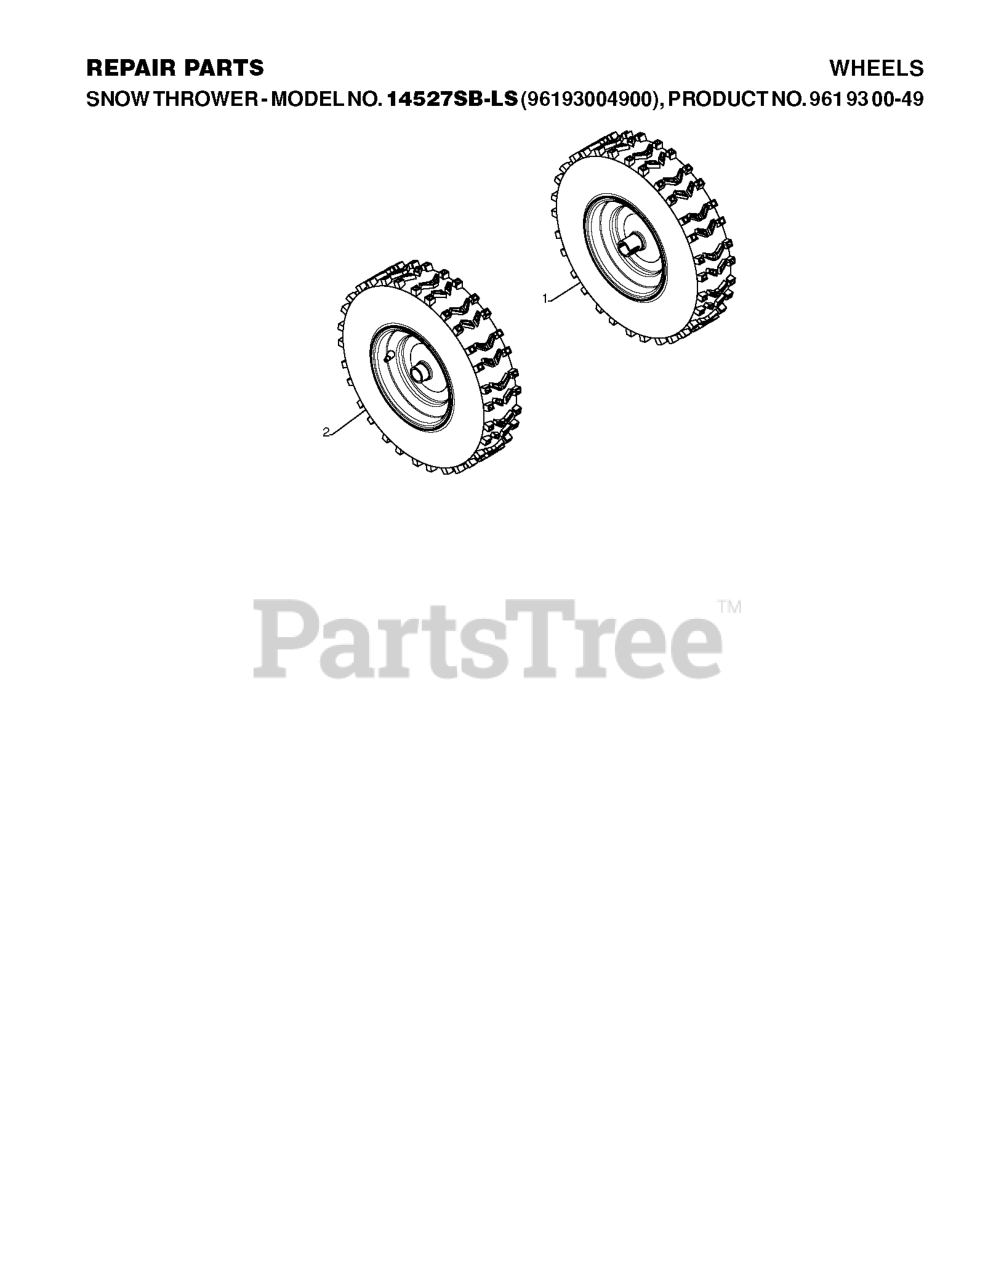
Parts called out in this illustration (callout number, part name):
1	WHEEL.ASM.LT.16"
2	WHEEL.ASM.RT.16.SILV.XTRAC.PS
8	ROD SHIFT FENDER ADJUST LT
9	CLUTCH.ELECTRIC.OGURA.EURO.
10	PIN COTTER
14	LOCKWASHER
15	BOLT HEX 5/16-18 GR 5
16	NUT.71038.31-18.HEX.NYLOCK
19	NUT
20	BOLT HEX 7/16-20X4-1/4"
21	KNOB.DUCKHEAD.1/2
22	ROD
24	NUT
25	SPRING BRAKE ROD
27	COTTER PIN
28	ROD, PARKING BRAKE
29	CAP
30	BRKT, TRNSXLE MNT 20"
34	SHAFT, FOOT PEDAL
35	BEARING.NYLON
37	DRIVE PIN
38	PULLEY.FLAT
42	WASHER
47	IDLER PULLEY
48	BELLCRANK, CLUTCH
49	RETAIN BELT
50	BOLT.3/8-16X1.50
52	LOCKNUT
53	LINK.CLUTCH.7.66.2005
55	SPRING, RETURN LT
56	SCREW.3/8-16
57	V-BELT 113"
62	PEDAL COVER T
63	PULLEY.ENGINE.CVX.LT
65	LOCKWASHER
66	KEEPER BELT ENGINE
71	STRAP TORQUE LH HYDRO
73	STRAP TORQUE RH HYDRO
74	SPACER AXLE
77	SQUARE KEY
81	ASM.CROSS.SHAFT.REAR.CRD.0510
82	SHIFT SPRING
83	WASHER
84	LINK.PNT.TRANSAXLE.0510.CRD
95	LINK
96	RETAINER M
120	NUT LOCK FLG 3/8-16 UNC
150	BUSHING.BELLCRANK.GRD.DR
151	WASHER 12/32X2X10GA
156	WASHER.SRRTD.5/16
158	BRACKET
159	RB HUB.SHIFT
161	BOLT
162	NUT.CROWNLOCK.1/4
165	RP BRACKET
166	CAPSCREW.HXHD.FLG.5/16-18X.625
167	BRACKET.SUPT.SHIFT.CRD
168	BOLT.SHOULDER.5/16-18X
169	PLATE.FASTENING.CROSS.SHAFT
172	LINK
181	BRACKET
182	BELT GUIDE
183	PULLEY.V-IDLER.GRND.DR
185	LINK
186	HUB.TAPERED.ROUND.CRD
187	BOLT.5/16-18X1.25
197	NYLINER SNAP 5/8" ID
199	BOLT SHOULDER 5/16-18 UNC
207	WASHER NYL
214	LEVER
215	ROD
243	BRACKET, ANTI-ROTATION
252	WASHER
254	SCREW 3/8-16X1
255	SHAFT
258	CLIP RETAINER
259	BRACKET
261	FLAT IDLER PULLEY
263	SCREW, 3/8-16X3/4
266	PROTECTOR
268	GUARD MUFFLER
275	WASHER
292	SPACER
295	PULLEY IDLER COMPOSITE
